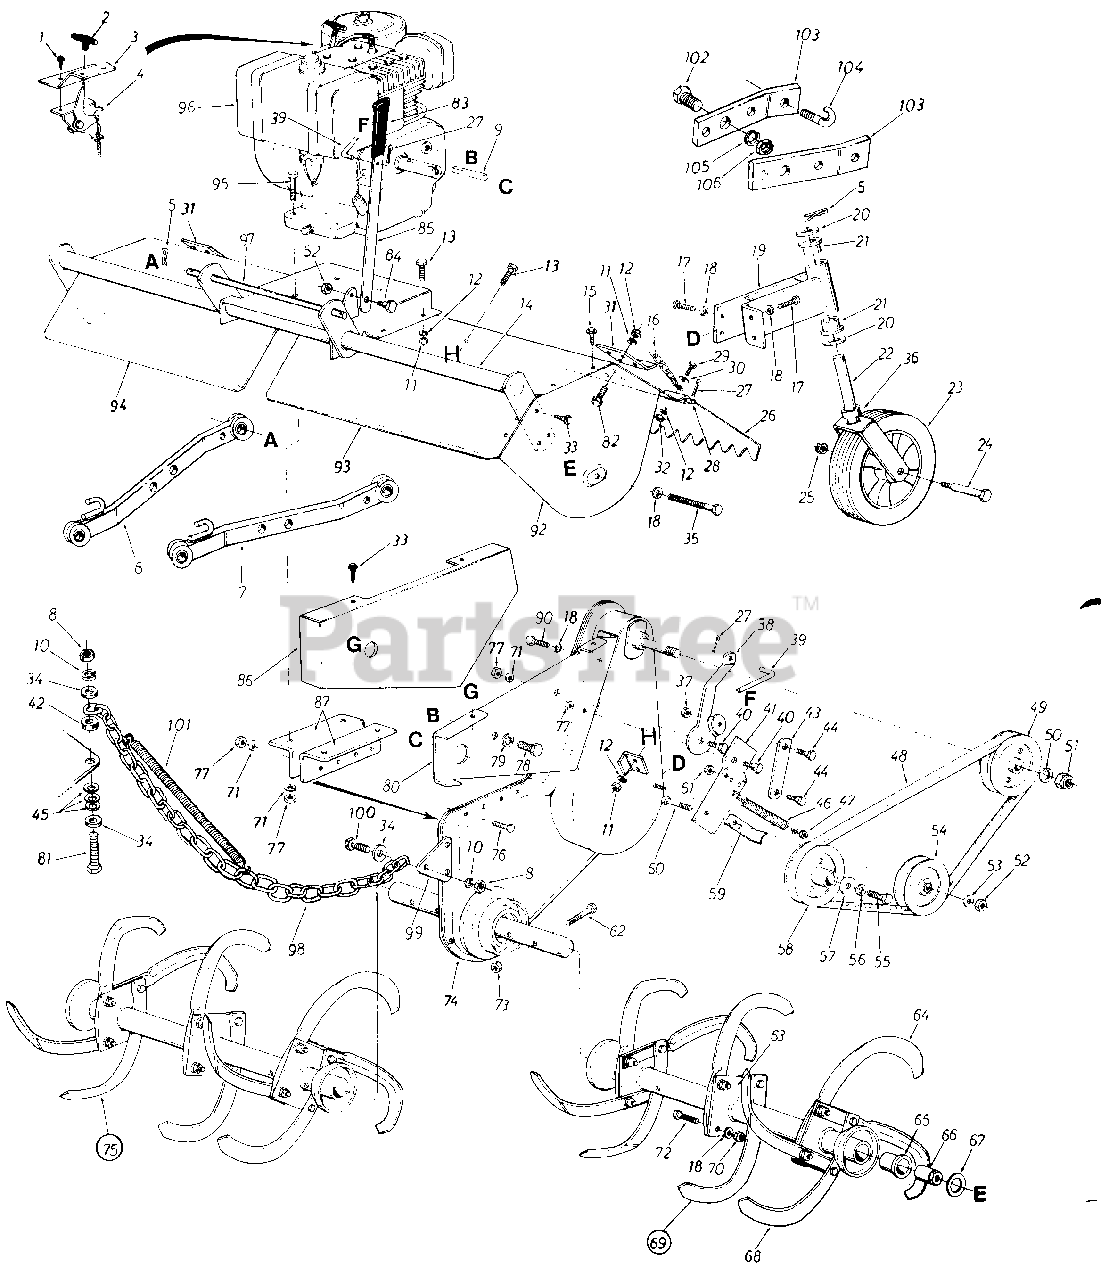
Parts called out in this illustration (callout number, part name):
1	Hex Wash. Hd. Self-Tap Scr. #8 x .50" Lg.
2	Throttle Control Knob-
3	Throttle Control Bracket
4	Throttle Control Ass'y. Comp.
5	Internal Cotter Pin
6	Draft Bar Ass'y.-R.H.
7	Draft Bar Ass'y.-L.H.
8	Hex Nut 3/8-24 Thd.*
9	Sq Key 1/4" x 1/4" x 2.00"
10	L-Wash. 3/8" I.D.*
11	Hex Nut 1/4-28 Thd.
12	L-Wash. 1/4" I.D.*
13	Hex Bolt 1/4-28 x .62" Lg.*
16	#2 Dog Chain x 20" Lg.
17	Hex Wash. Hd. Self-Tap Scr. 318-24 x .75" Lg.
18	L-Wash. 3/8" I.D.*
21	Flange Bearing 3/4" I.D. x 1.00" O.D.
24	Shoulder Bolt .623" I.D. x 3.62" Lg.
25	Hex Cent. L-Nut 7/16-14 Thd.
28	L.H Flap Rod
29	Hex Bolt 1/4-20 x .62" Lg.*
30	Fl-Wash. 1/4 " I.D.
33	Hex Wash. Hd. Self-Tap Scr. 1/4" x .62" Lg.
34	Fl-Wash. .385" I.D. x 1.0" O.D. x .135 Thk.
35	Hex Bolt 3/8-16 x 1.25" Lg.*
36	Spacer .752" I.D. x 1.25"O.D.
37	Hex Cent. L-Nut 5/16-18 Thd.
40	Shoulder Bolt 7116" Dia. x 1.75" Lg.
45	Fl-Wash. .406" I.D. x .74" O.D. x .063 Thk.
46	Extension Spring .62" O.D. x 6.12" Lg.
47	Hex Crown Nut 3/8-24 Thd.
48	"V"-Belt 1/2" x 43" Lg. (Kevlar)
49	1/2" "V"-Pulley 4.75" O.D. x .625" Bore
50	L-Wash. 5/8" I.D.*
51	Hex Ins. L-Nut 5/8-18 Thd.
52	Hex Cent. L-Nut 3/8-16 Thd.
53	Fl-Wash. 3/8" I.D.
54	Idler Pulley 4.0" O.D.
55	Hex Bolt
56	L-Wash. 7/16" I.D.*
57	Fl-Wash. 7/16" I.D. x 1.38" O.D.
58	1/2" "V"-Pulley.475" O.D. x 1.001" Bore
61	Hex Cent. L-Nut 5/16-18 Thd.
62	Hex Bolt 7/16-14 x 2.00" Lg.
66	Spacer
67	Thrust Wash. 1/2" I.D. x 1.55" O.D.
71	L-Wash. 5/16" I.D.
72	Hex Bolt 3/8-24 x 1.5" Lg.*
73	Hex Cent. L-Nut 7/16-14 Thd.
77	Hex Nut 5/16-18 Thd.
78	Hex Bolt 1/2-20 x .88" Lg. (Grade 5)
79	L-Wash. 1/2" I.D.
80	Clutch Support Bracket
81	Hex Bolt 3/8-24 x 1.75" Lg.
82	Hex Bolt 1/4-28 x .75" Lg.
83	Plastic Grip
84	Shoulder Bolt .498 Dia. x .212 Lg.
85	Clutch Handle
96	8 H.P. Engine
97	Tiller Mounting Shaft 16" Lg.
98	Chain 23" Lg.
99	Tiller Mounting Bracket
100	Hex Bolt 3/8-24 x 1.25" Lg.*
101	Extension Spring
102	Hex Bolt 5/8-18 x 1.62" Special
103	Drag Link Extension
104	Hitch Chain Hook
105	L-Wash. 5/8" I.D.*
106	Hex Jam Nut 5/8-18 Thd.
